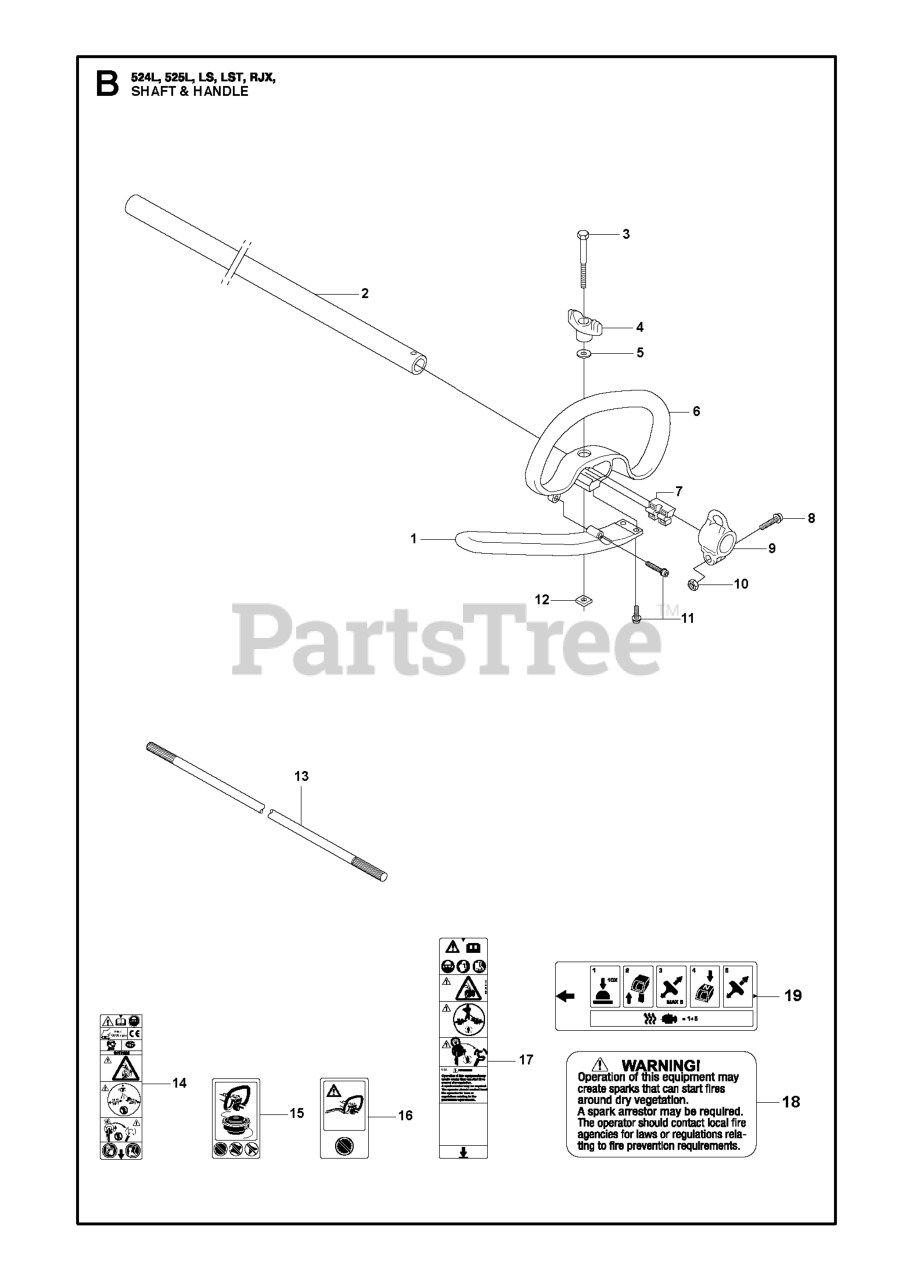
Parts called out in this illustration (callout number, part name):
1	HANDLE
2	TUBE
3	BOLT
3	SCREW M6X50
4	KNOB
5	WASHER
6	HANDLE
7	SPACER PLASTIC
8	SCREW
9	HARNESS HOLDER
10	NUT
11	SCREW IHSCFTO
13	DRIVESHAFT
14	LABEL WARNING 110DB/10000RPM
15	DECAL WARNING "NO BLADES"
16	DECAL
17	LABEL WARNING TRIMMERS AND BRU
18	DECAL SPARK ARRESTOR WARNING
19	DECAL START REMINDER 523/525
